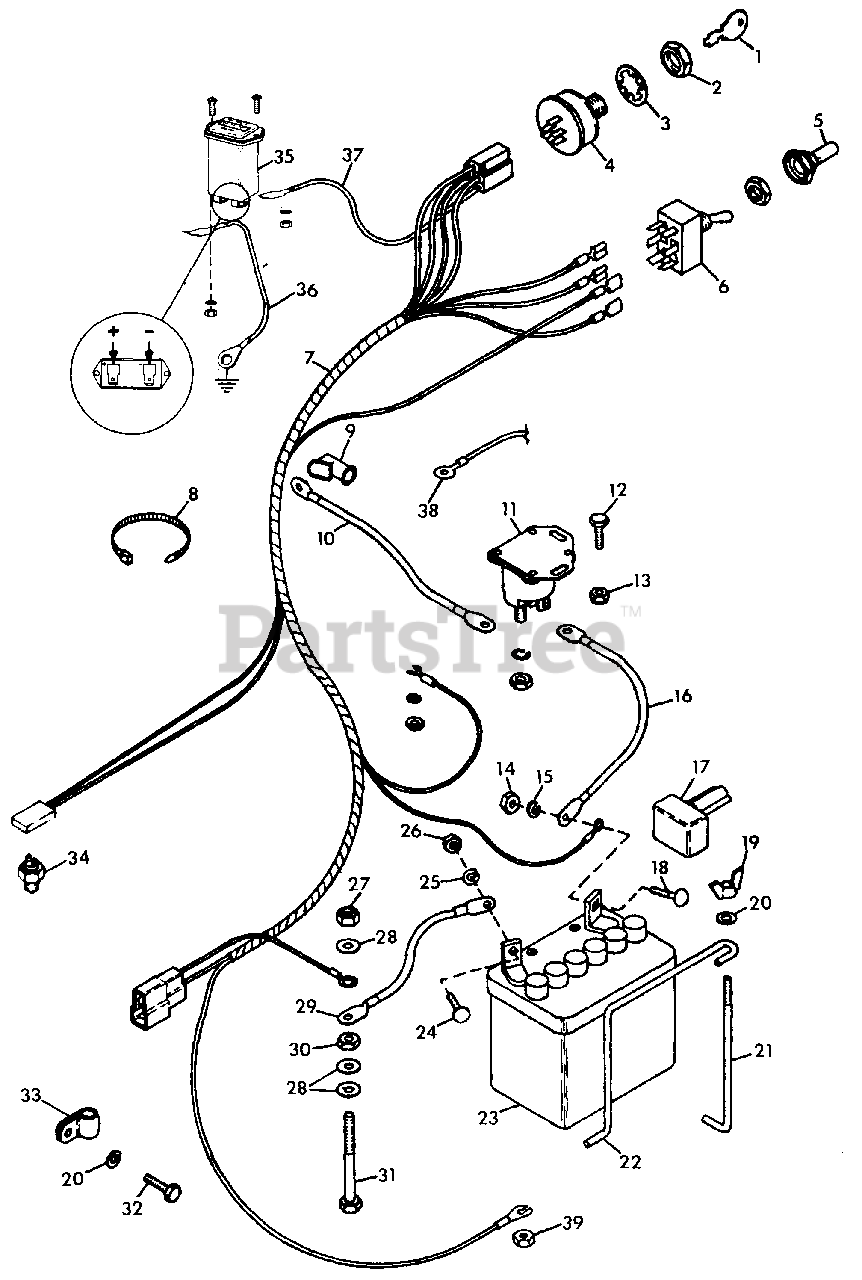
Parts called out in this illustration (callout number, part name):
1	KEY, IGNITION SWITCH
2	NUT, JAM 9/16-24
3	WASHER, LOCK 9/16
4	SWITCH, IGNITION
5	BOOT, TOGGLE SWITCH
6	SWITCH, TOGGLE
7	HARNESS, WIRING
8	TIE, CABLE
9	BOOT, BATTERY CABLE
10	CABLE, SOLENOID TO STARTER
11	SWITCH, MAGNETIC
12	BOLT, HEX 1/4-20X.625
13	NUT, SPEED 1/4-20
14	NUT, HEX 5/16-18
15	WASHER, LOCK 5/16 REG.
16	CABLE, BATTERY TO SOLENOID
17	BOOT, BATTERY CABLE
18	BOLT, 5/16-18X.625 RD HD SQ NK
19	NUT, WING 1/4-20
20	WASHER, FLAT .281X.625X.065
21	HOOK, BATTERY HOLD DOWN
22	BRACKET, BATTERY HOLD DOWN
23	BATTERY, 12 VOLT
24	BOLT, 1/4-20X.625 RD HD SQ NK
25	WASHER, LOCK 1/4
26	NUT, HEX 1/4-20
27	NUT, LOCK 5/16-18
28	WASHER, FLAT .344X.688X.065
29	CABLE, NEGATIVE BATTERY
30	NUT, HEX 5/16-18
31	BOLT, HEX 5/16-18X2.00
32	BOLT, HEX 1/4-20X1.00
33	CLAMP
34	SWITCH, NEUTRAL START
35	HOURMETER
36	WIRE, INSTRUMENT PANEL
37	WIRE, HOURMETER
38	TERMINAL, RING TONGUE
39	NUT, HEX 8-32
